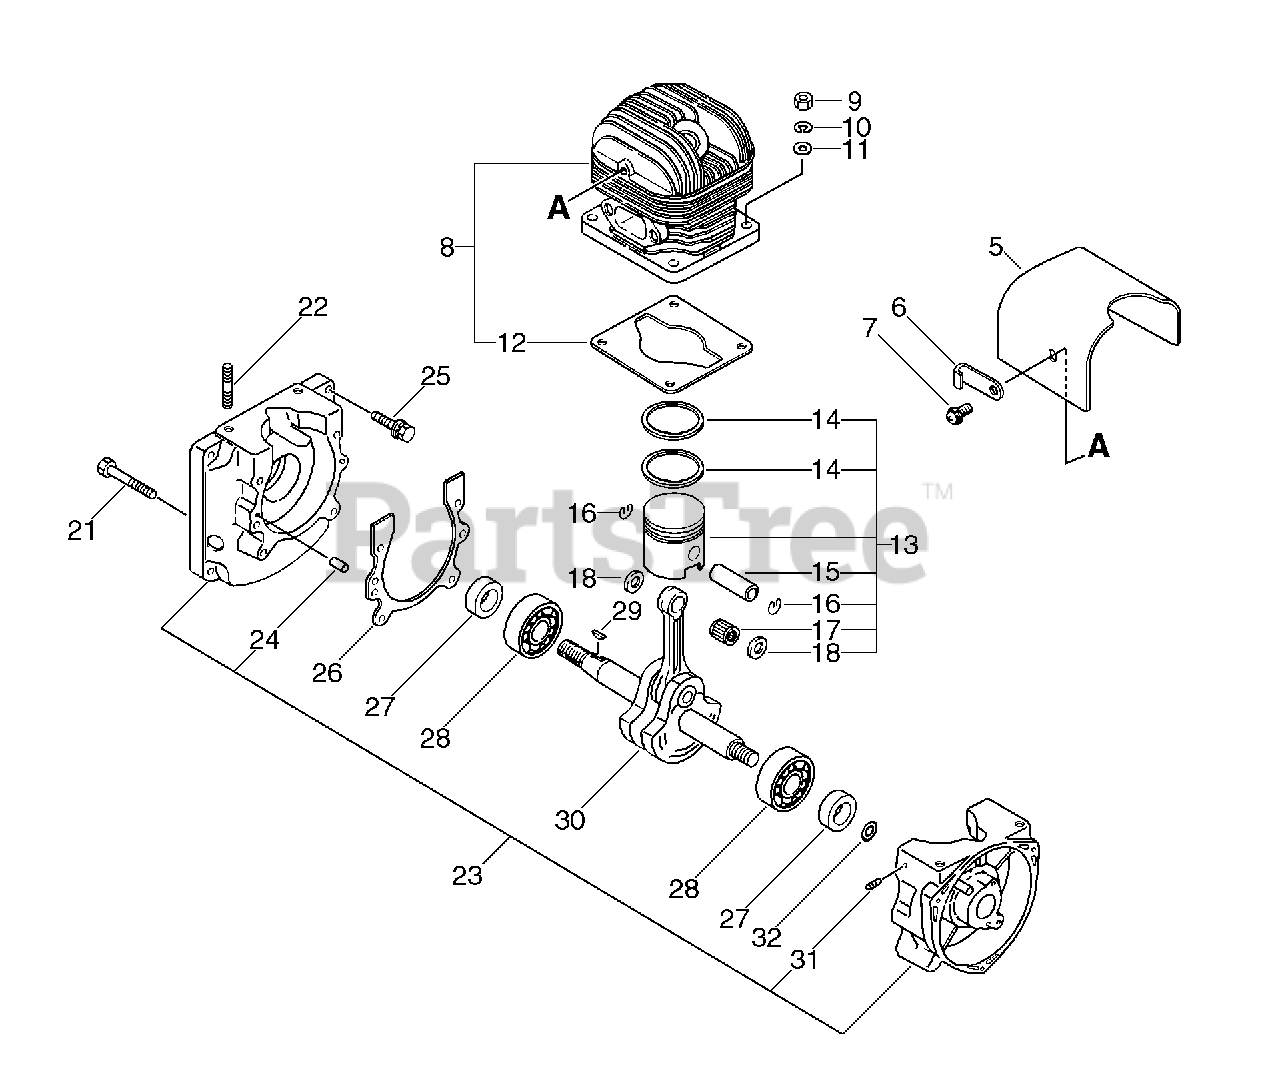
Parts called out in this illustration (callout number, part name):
5	SHIELD, CYLINDER
7	BOLT - 6X10
8	CYLINDER KIT
9	LOCKNUT - 6
10	LOCKWASHER - 6
11	WASHER - 6
12	GASKET, CYLINDER
13	PISTON KIT
14	RING, PISTON
15	PIN, PISTON
16	RING, RETAINING - 8
17	BEARING, NEEDLE
18	SPACER, PISTON
23	CRANKCASE KIT
24	PIN - LOCATING
25	BOLT - 6X25
26	GASKET, CRANKCASE
27	SEAL, OIL
28	BEARING, BALL - 6202
30	CRANKSHAFT ASSY
31	CONNECTOR
32	WASHER - 10
